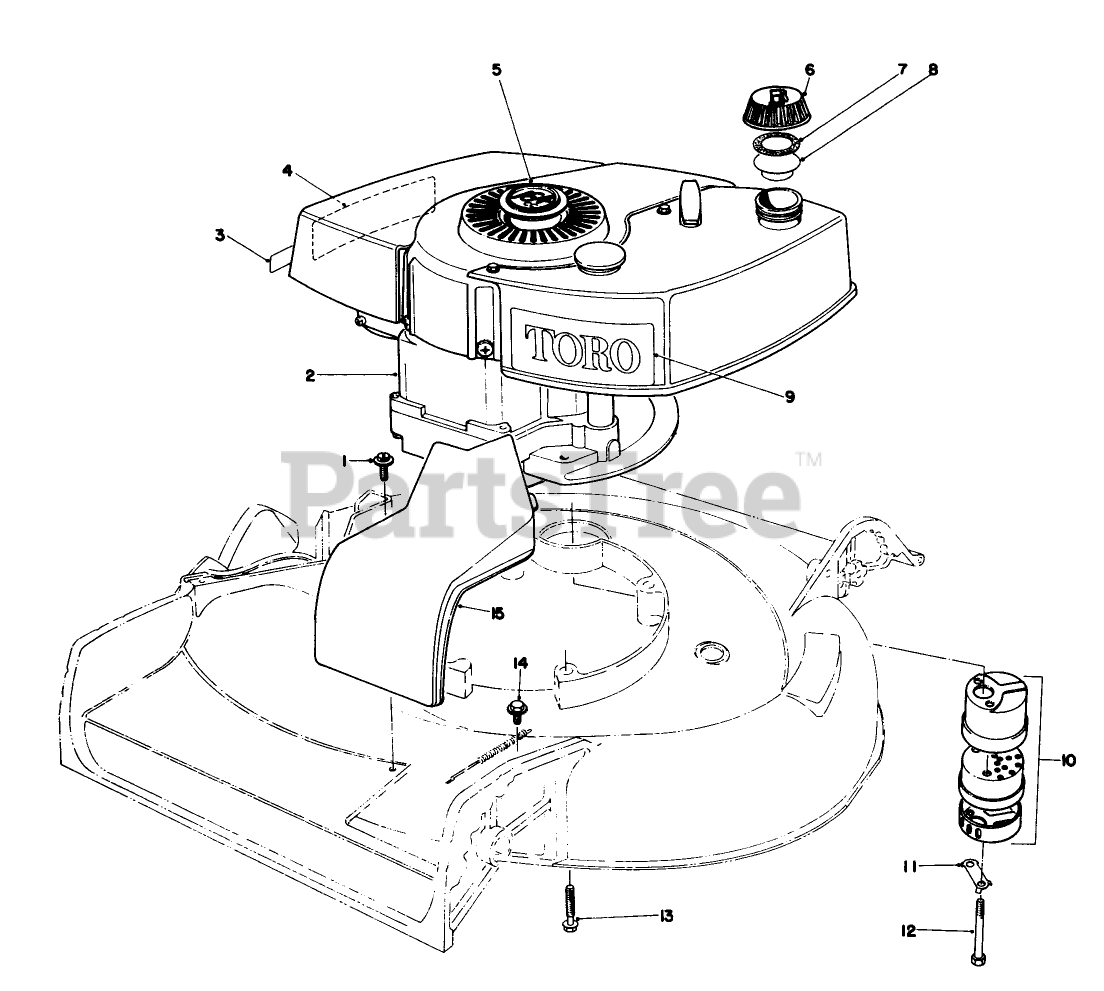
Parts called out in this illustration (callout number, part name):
1	SCREW
2	Engine
7	GASKET
10	MUFFLER ASM
11	CLIP - LOCKING
12	SCREW-HH
13	3/8-16 X 2-3/4 CAPSCR
14	SCREW-THD ROLL, HWH
